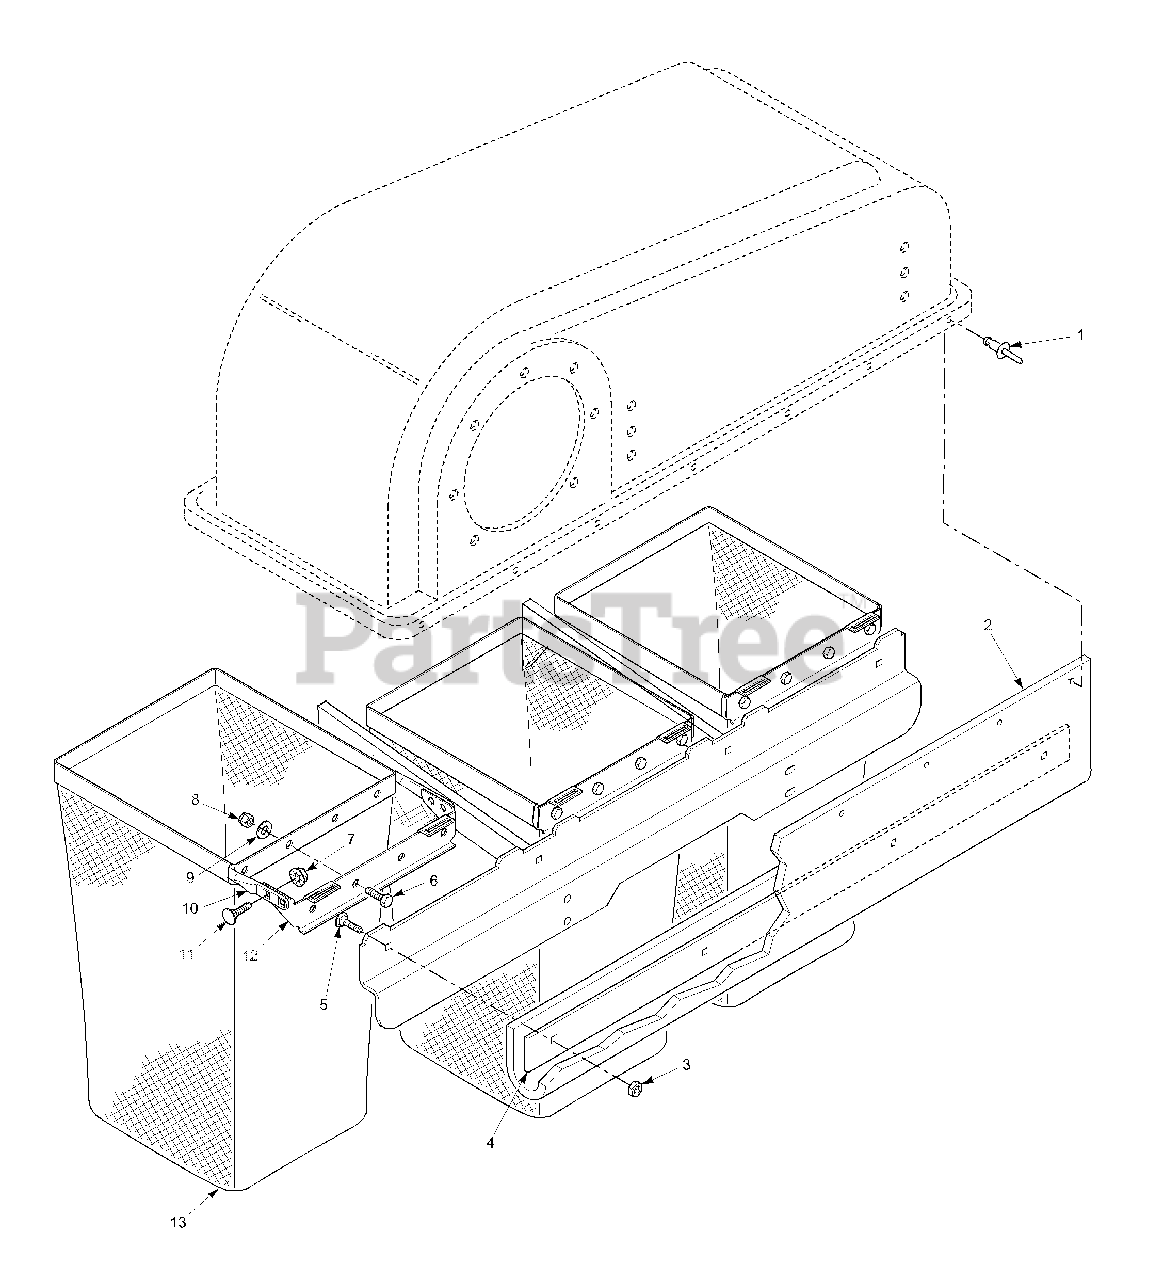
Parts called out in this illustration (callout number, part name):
1	Pop Rivet, 3/16 x .652
2	Seal, Hood
3	Lock Nut, 1/4-20 Center Lock
4	Retainer, Seal
5	Bolt, Carr. 1/4-20 x 3/4"
6	Bolt, Hex Head 5/16-18 x 3/4"
7	Nut, Serrated Flange 5/16-18
8	Nut, Elastic Stop 5/16-18
9	Flatwasher, 5/16-.375 x .875 x .083
10	Tube, Bag Support
11	Bolt, Carr. 5/16-18 x 3/4"
12	Mount, Bag Frame Tube
13	Bag Assembly, GC-STT
